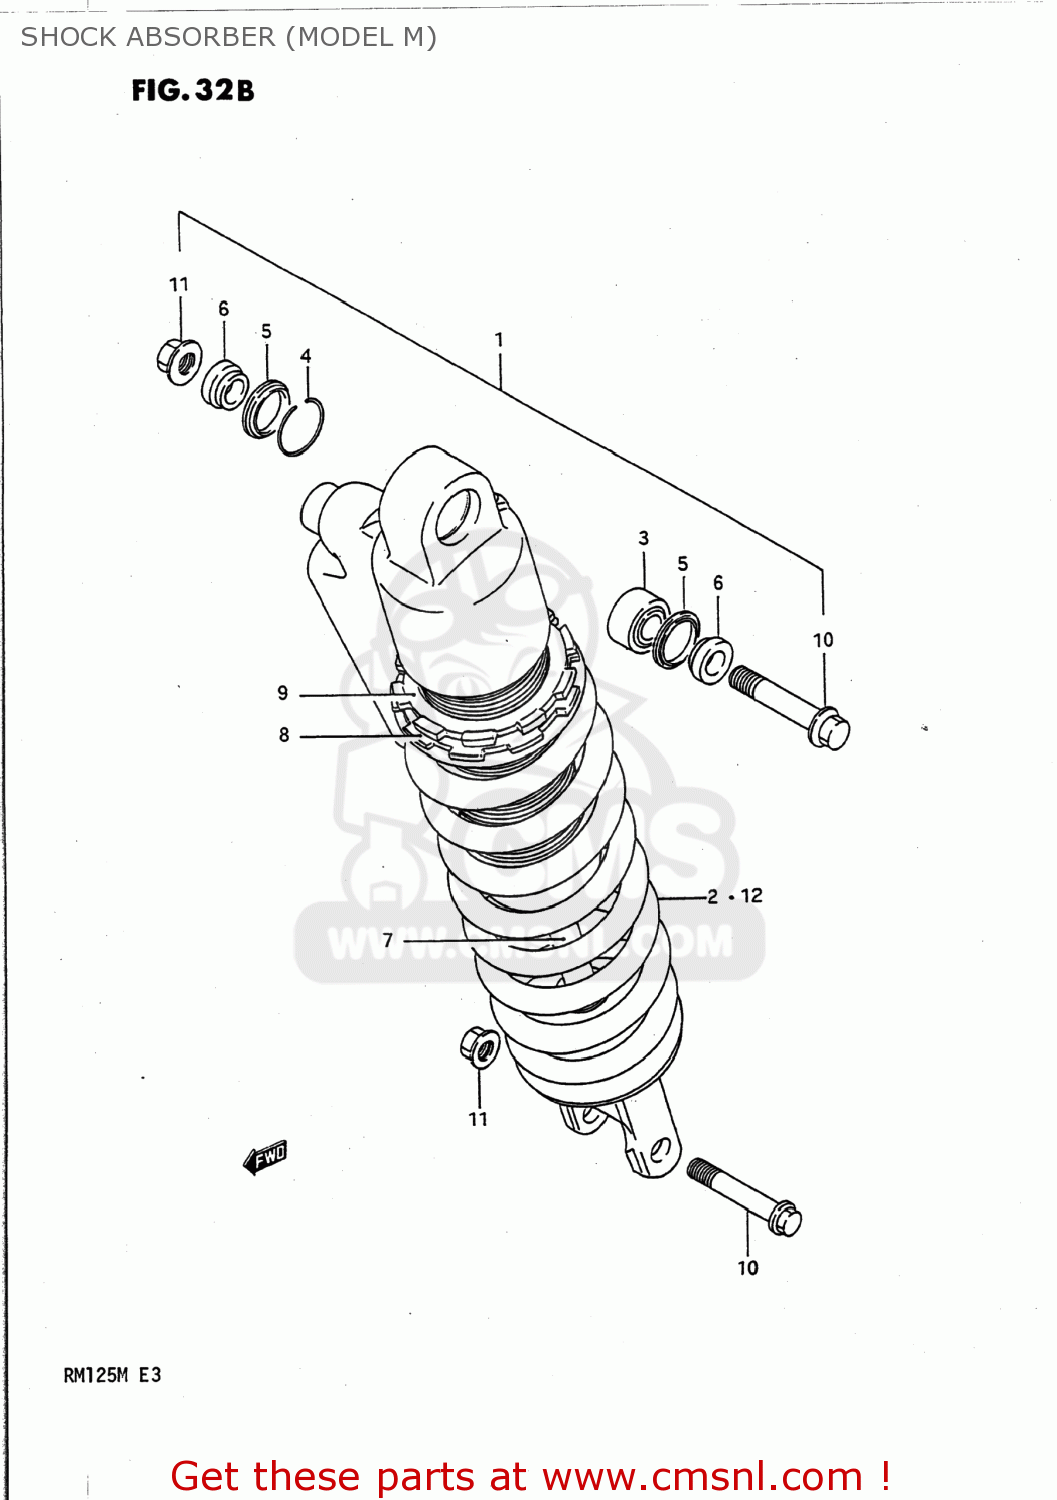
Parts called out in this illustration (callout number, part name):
1	ABSORBER ASSEMBLY,REAR SHOCK
2	SPRING
3	BEARING,REAR SHOCK ABSORBER
4	RING,STOPPER
5	SEAL,DUST
6	COLLAR
7	ROD,PISTON
8	GUIDE,SPRING
9	NUT
10	BOLT,REAR SHOCK ABSORBER
11	NUT
12	SPRING
